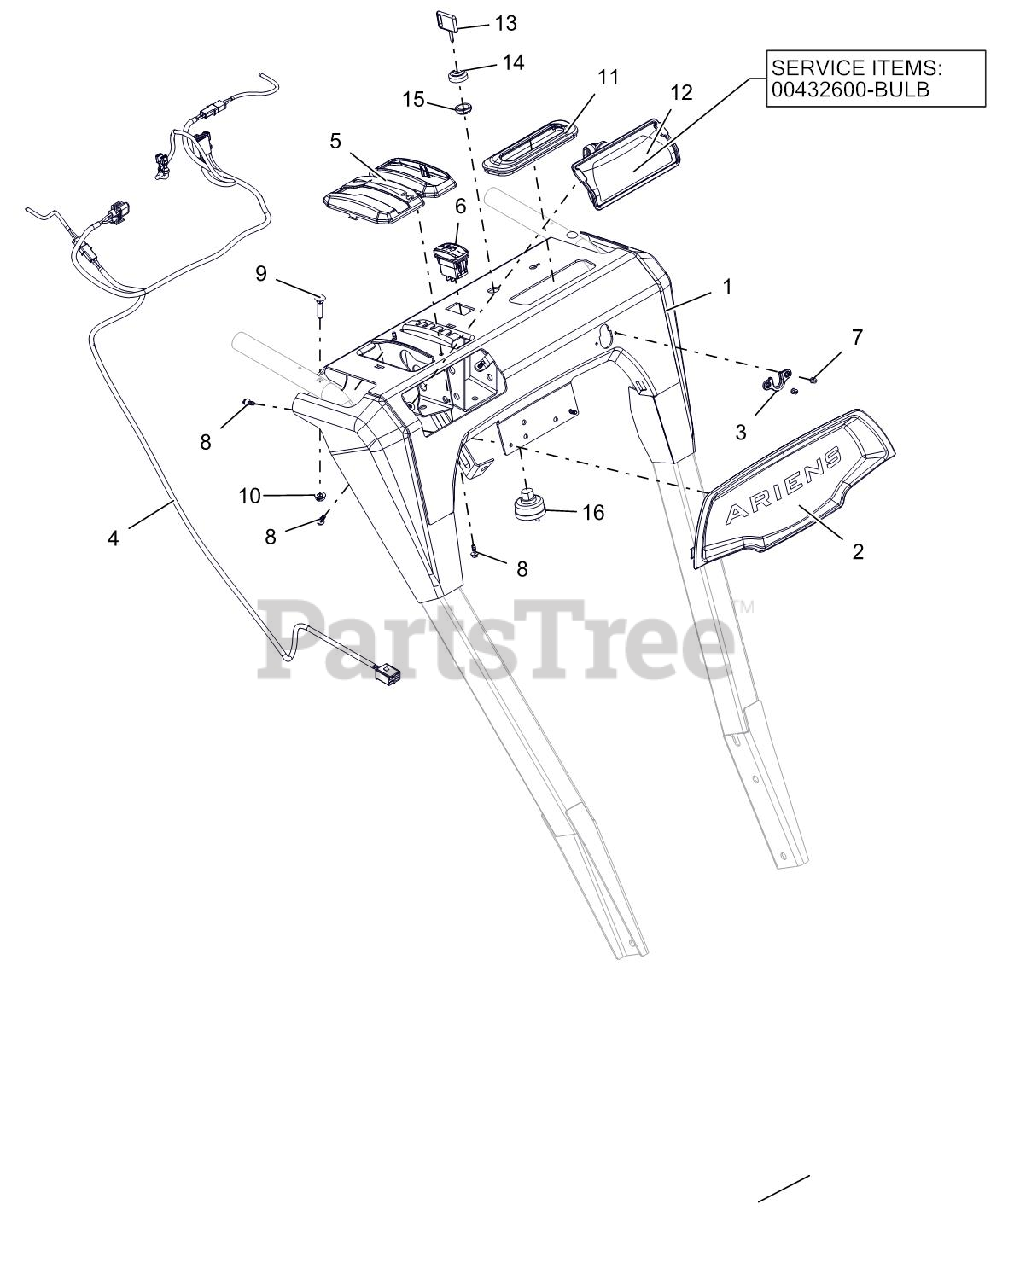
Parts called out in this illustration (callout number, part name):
1	PANEL, DASH-HYDRO 12V W/DECAL
2	BEZEL, DASH - ARIENS LG DASH
3	GROMMET, CABLE, QUICK TURN 2
4	HARNESS,ELEC - HANDLEBAR 12V
5	BEZEL, SHIFT - HYDRO SNOW
6	SWITCH,ROCKER SPST-ON/OFF
7	RVT-POP #43 .125X.313 STL ZINC
8	SCR-TAP #10X.50 BOSS INDHXHD
9	BLT-RDHDXLSQNK.25-20X1.25 G5ZC
10	@NUT-LK-CTR-FLG .25-20 YWZC
11	GROMMET, BOOT, QUICK TURN
12	BULB, LIGHT-HALOGEN 20W
12	HEADLIGHT ASY, HALO 20W 2SHOT
13	KEY -W/CAP
14	CAP - IGNITION SWITCH
15	NUT-PANEL .625-32 GRECO
16	IGNITION SWITCH ASSEMBLY
